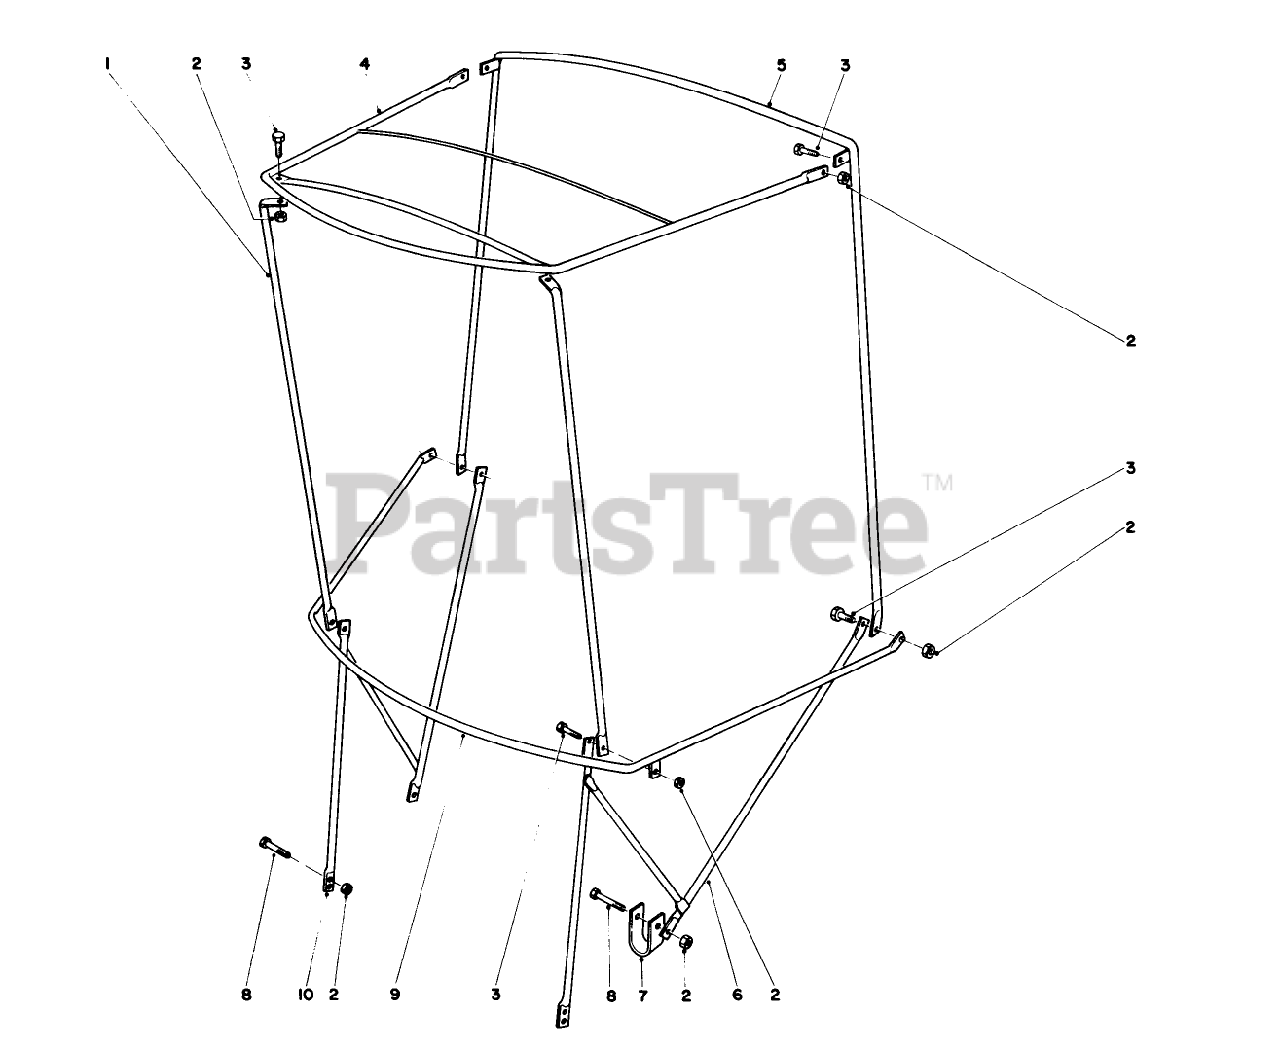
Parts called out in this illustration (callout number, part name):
3	SCREW-HH
8	SCREW-HH
10	Attaching Bracket R.H.
